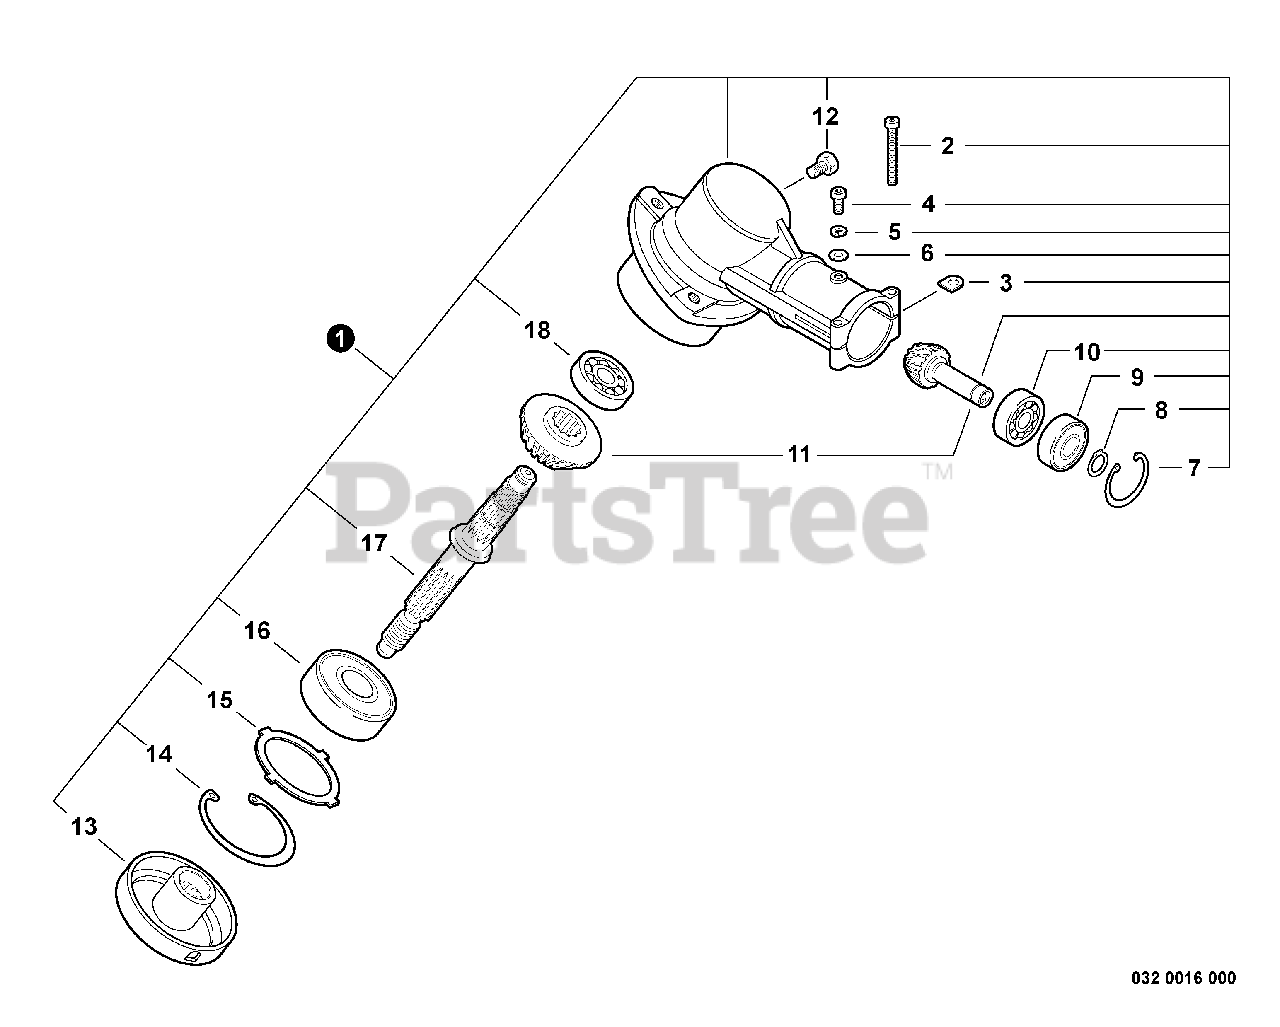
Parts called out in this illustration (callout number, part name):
1	GEAR CASE ASSY
2	SCREW - 5X25
4	SCREW - 5X10
5	LOCKWASHER - 5
6	WASHER - 5
7	RING, RETAINING - 22
8	RING, RETAINING - 10
9	BEARING, BALL - 6900Z
10	BEARING, BALL - 6900
11	GEAR SET - BEVEL
12	BOLT - 8X8
13	ADAPTOR, BLADE - UPPER
14	RING, RETAINING - 32
16	BEARING, BALL - 6201
17	GEAR - SHAFT
18	BEARING, BALL - 609
